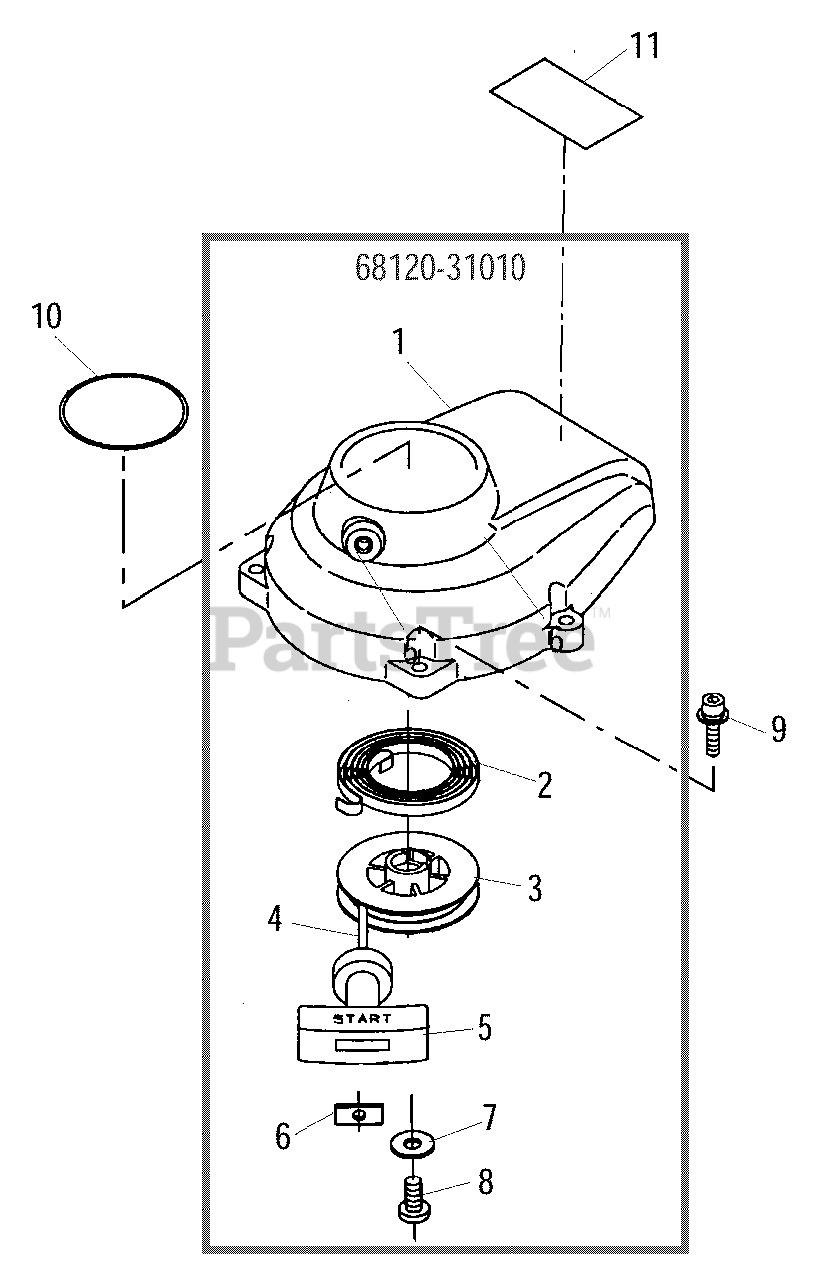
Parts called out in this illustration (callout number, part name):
1	CASE, STARTER
2	SPRING, REWIND
3	REEL, ROPE
4	ROPE, STARTER
5	GRIP, STARTER
6	RETAINER, ROPE
7	WASHER
8	SCREW
9	SCREW - 5X20
10	LABEL - MODEL
11	LABEL - NAME
68120-31010	STARTER ASSY
